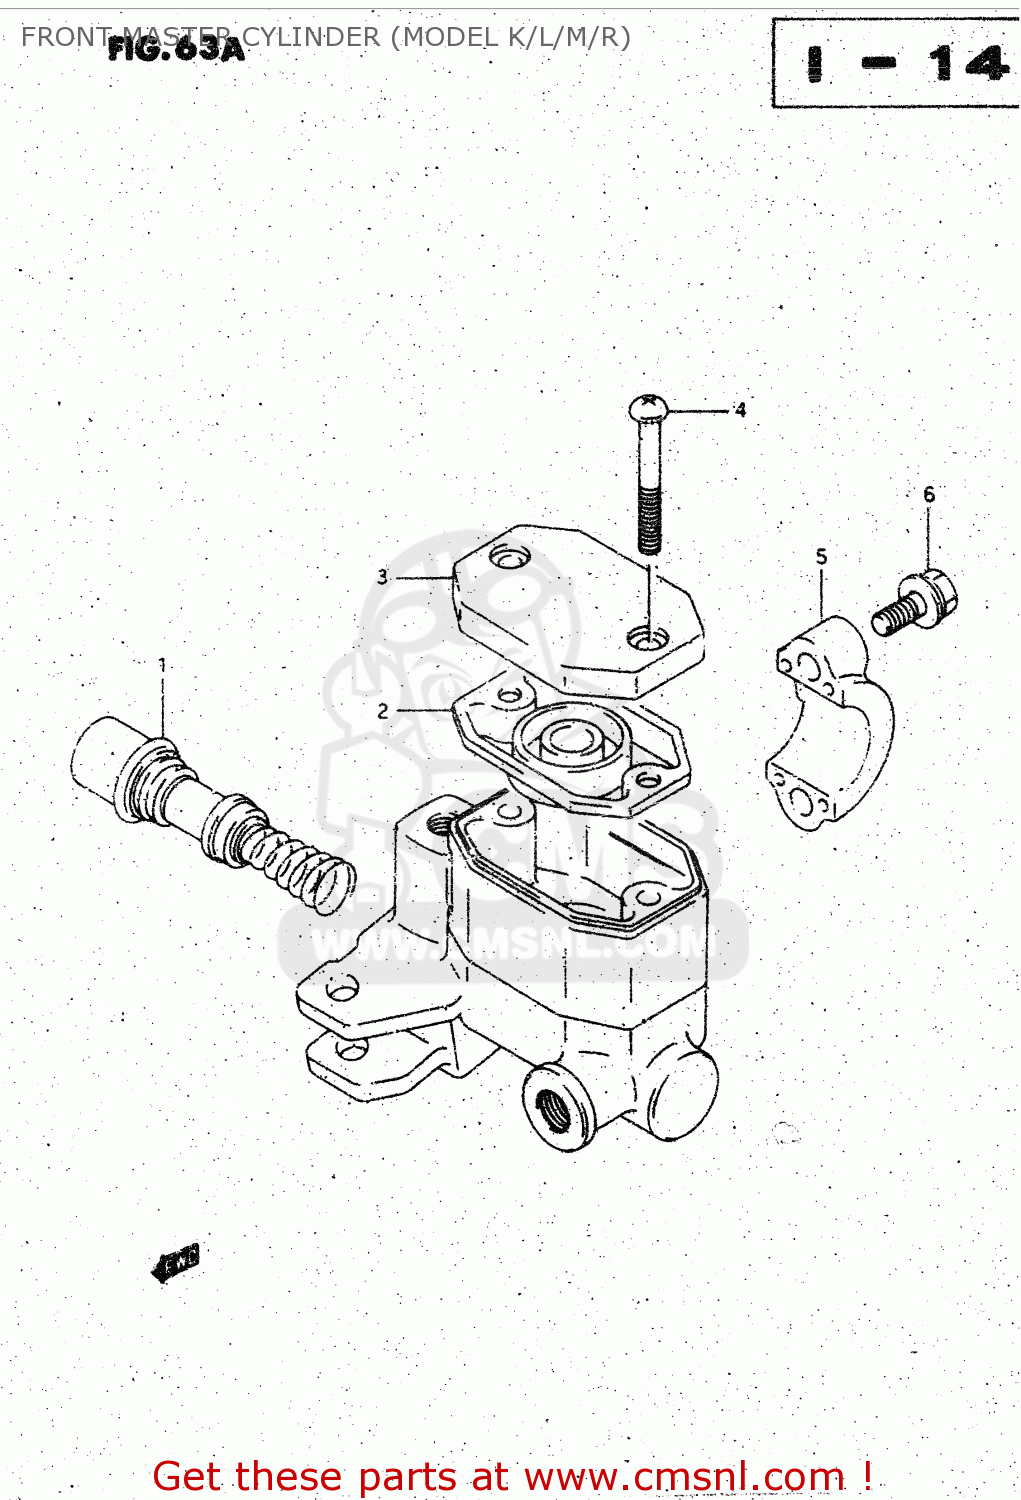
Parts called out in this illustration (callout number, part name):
1	PISTON & CUP SET
2	DIAPHRAGM
3	CAP,RESERVOIR
4	SCREW
5	HOLDER
6	BOLT
